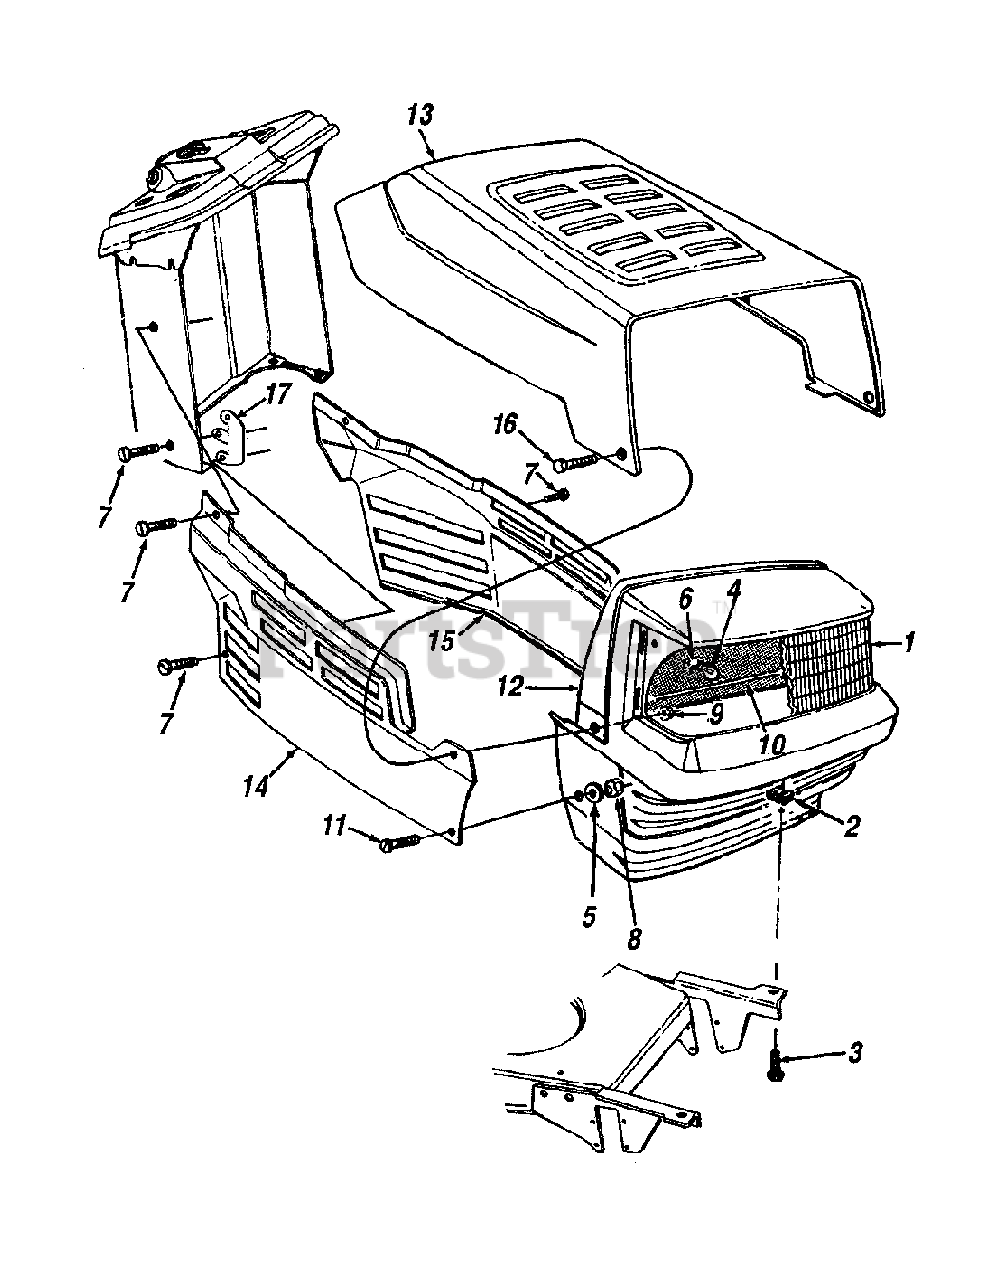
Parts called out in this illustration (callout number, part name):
1	Lens
2	U-Nut 5/16-18 Thd.
3	Hex Bolt 5/16-18 x .75"
4	Bulb
5	Bell Washer 1/4" I.D.
6	Socket
7	Hex TT-Tap. Screw 1/4-20 x .5"
8	Hex Nut 1/4-20 Thd.
9	Flange Lock Nut 1/4-20 Thd.
10	Grille Reflector Label
11	Pan Hd. Scr. 1/4-20 x .75"
12	Grille
